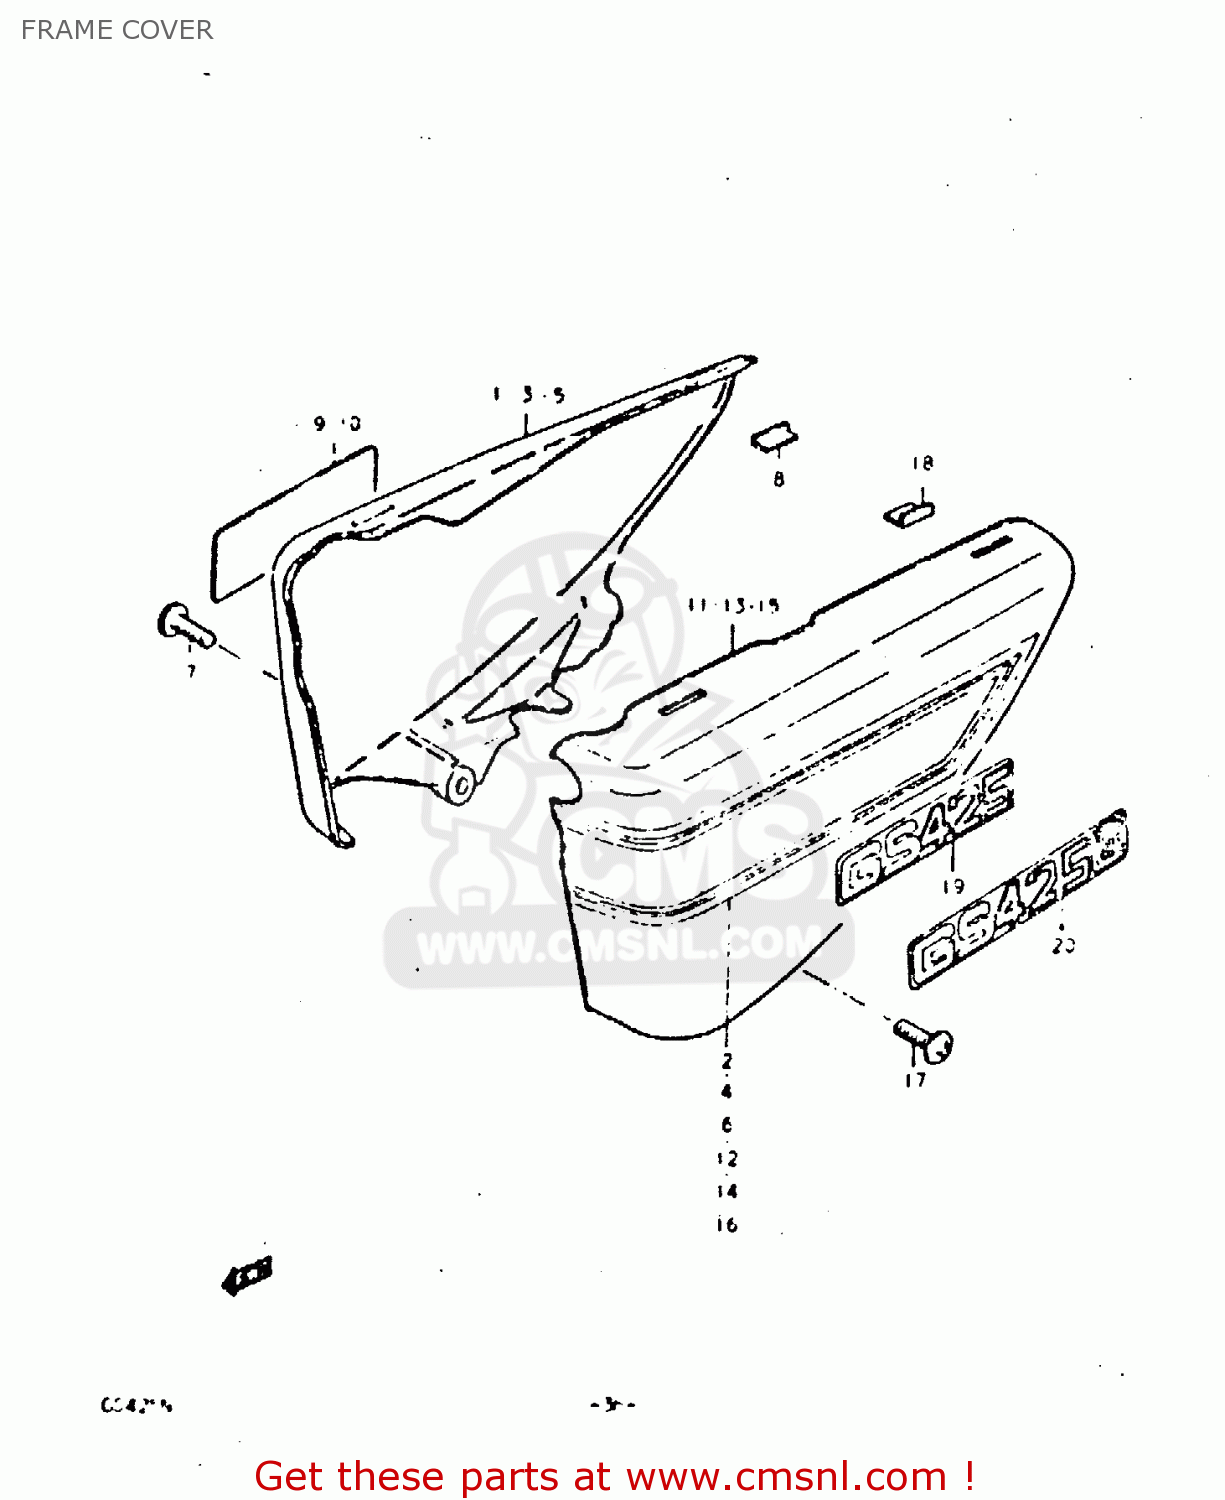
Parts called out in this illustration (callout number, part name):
1	COVER,FRAME,R(BLACK)
2	TAPE, RH
3	COVER, FRAME RH
4	TAPE, RH
5	COVER, FRAME RH
6	TAPE, RH
7	SCREW
8	CUSHION,FRAME COVER
10	EMBLEM,FRAME COVER
11	COVER,FRAME,LEFT
12	TAPE, LH
13	COVER, FRAME LH
14	TAPE, LH
15	COVER, FRAME LH
16	TAPE, LH
17	SCREW
18	CUSHION,FRAME COVER
20	EMBLEM,FRAME COVER
